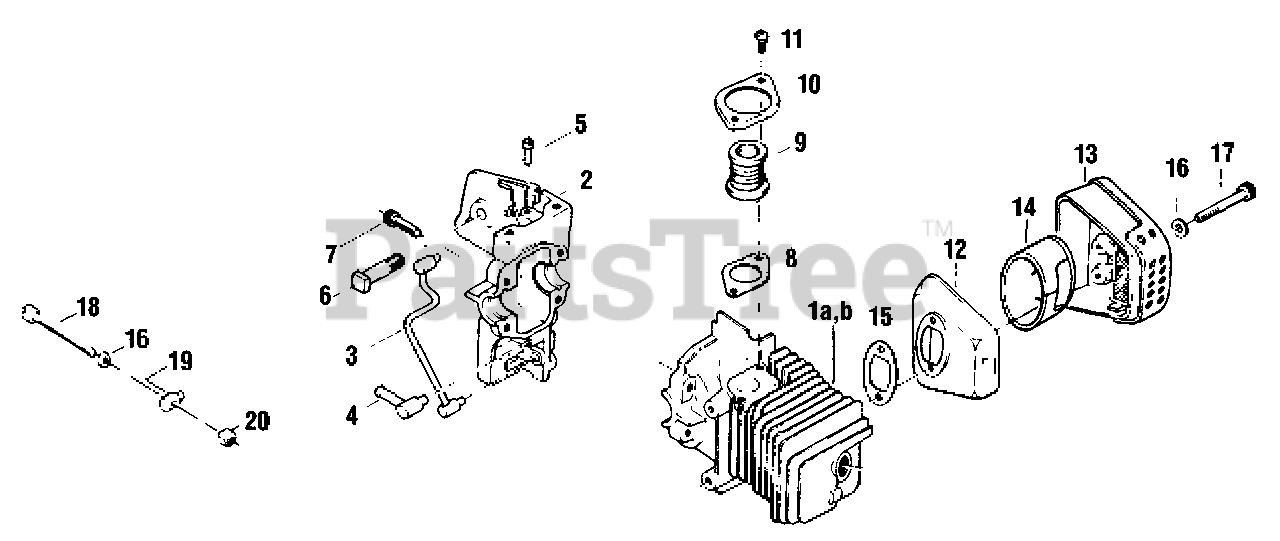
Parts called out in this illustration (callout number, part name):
1A	CYLINDER
1B	CYLINDER
2	CRANKCASE
3	TUBE, CRANKCASE OIL
4	ELBOW
5	CONNECTOR, PULSE
6	STUD, GUIDE BAR
7	BOLT M5×18
8	GASKET
9	BOOT
10	BRACKET, BOOT
11	SCREW
12	MUFFLER BASE
13	COVER, MUFFLER
14	MUFFLER PIPE
15	GASKET, EXHAUST
16	WASHER, FLAT 5.5×10×0.8
17	BOLT
18	SCREW, ADJUST
19	STUD, ADJUST
20	LOCKNUT
